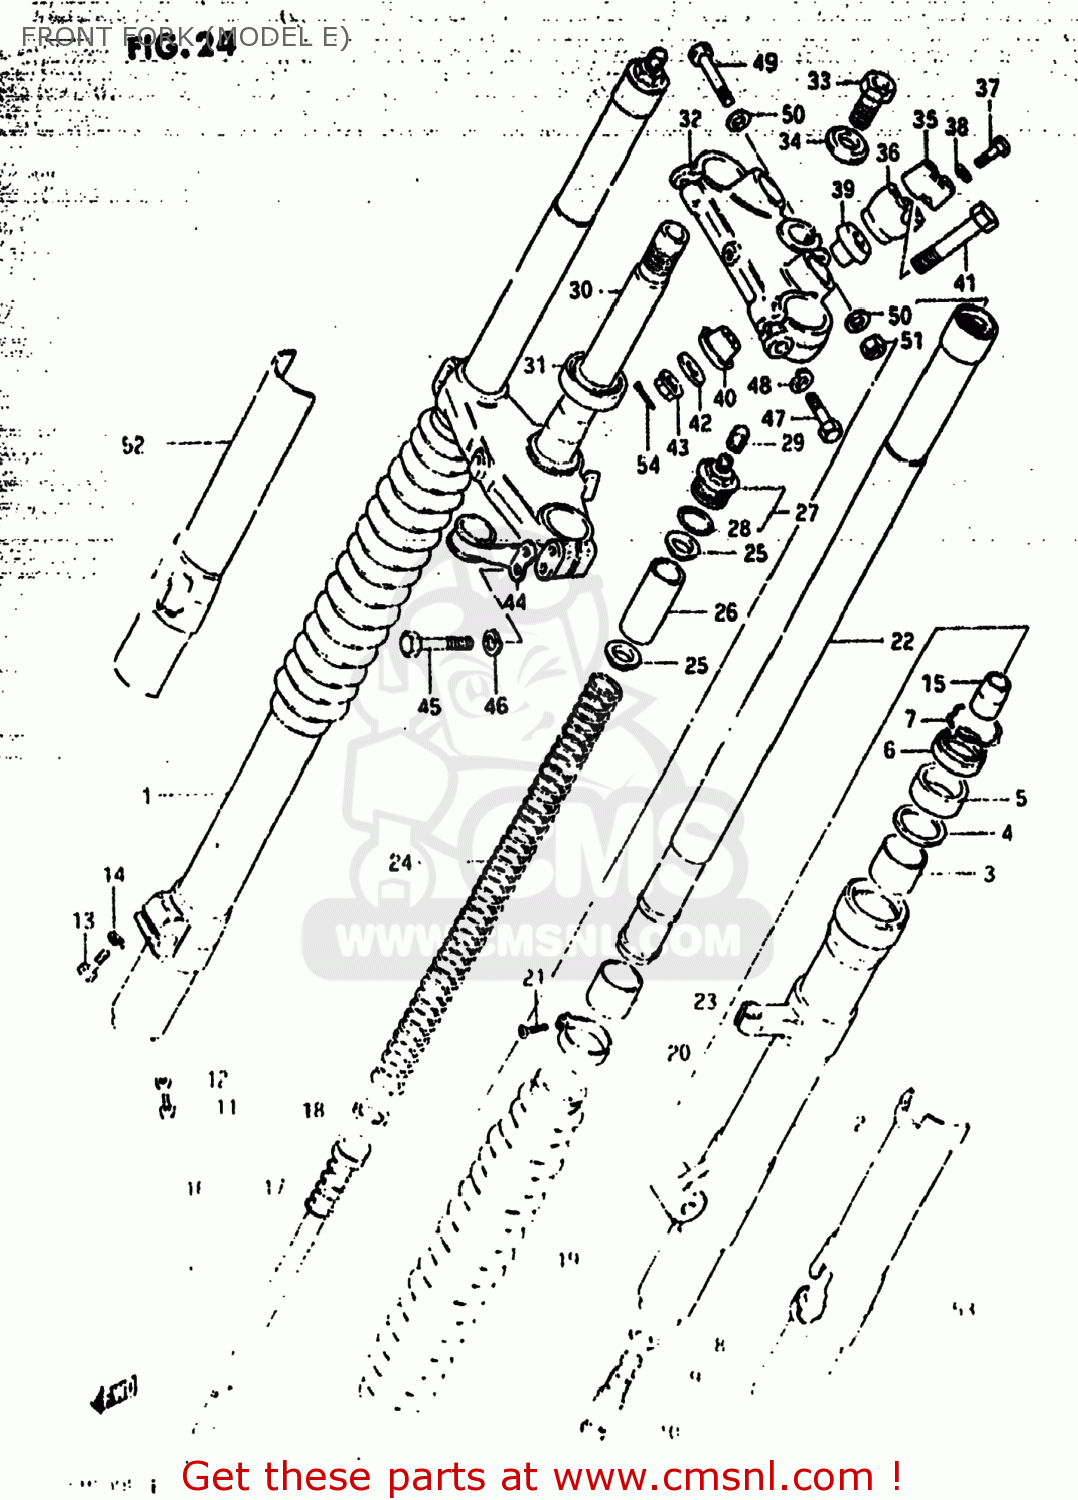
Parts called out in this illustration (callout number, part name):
1	TUBE,OUTER,RIGHT
2	TUBE,OUTER,LEFT
3	METAL,SLIDE
4	WASHER
5	SEAL,OIL
6	SEAL,DUST
7	RING,STOPPER
8	GASKET,FORK CYLINDER
9	VALVE,DF
10	CAP,FRONT FORK DF
11	SCREW 4X6
12	GASKET,DRAIN,PLUG (NAS)
13	BOLT (8X30)
14	WASHER,LOCK,8.
15	PIECE,FRONT FORK OIL LOCK
16	CYLINDER,FRONT FORK
17	SPRING,REBOUND
18	RING,FRONT FORK PISTON
19	BOOT,FRONT FORK COVER
20	BAND,BOOT,UPPER
21	SCREW 4X10
22	TUBE,FORK,INNER
23	PISTON
24	SPRING,FRONT FORK
25	GUIDE,FRONT FORK SPRING
26	SPACER,FRONT FORK SPRING
27	CAP,FORK INNER TUBE
28	O RING
29	CAP
30	STEM,STEERING
31	BEARING
32	HEAD,STEERING STEM
33	BOLT
34	WASHER
35	HOLDER,HANDLEBAR
36	HOLDER,HANDLE LWR
37	BOLT
38	WASHER,LOCK,8.
39	DAMPER,UPR
40	DAMPER,LWR
41	BOLT,HANDLE HOLDER
42	WASHER,HANDLEBAR HOLDER
43	NUT
44	GUIDE,CABLE
45	BOLT 8X40
46	WASHER,LOCK,8.
47	BOLT
48	LOCK WASHER
49	BOLT 8X50
50	WASHER
51	NUT
52	PROTECTOR,RIGHT
53	PROTECTOR
54	PIN 20X20
